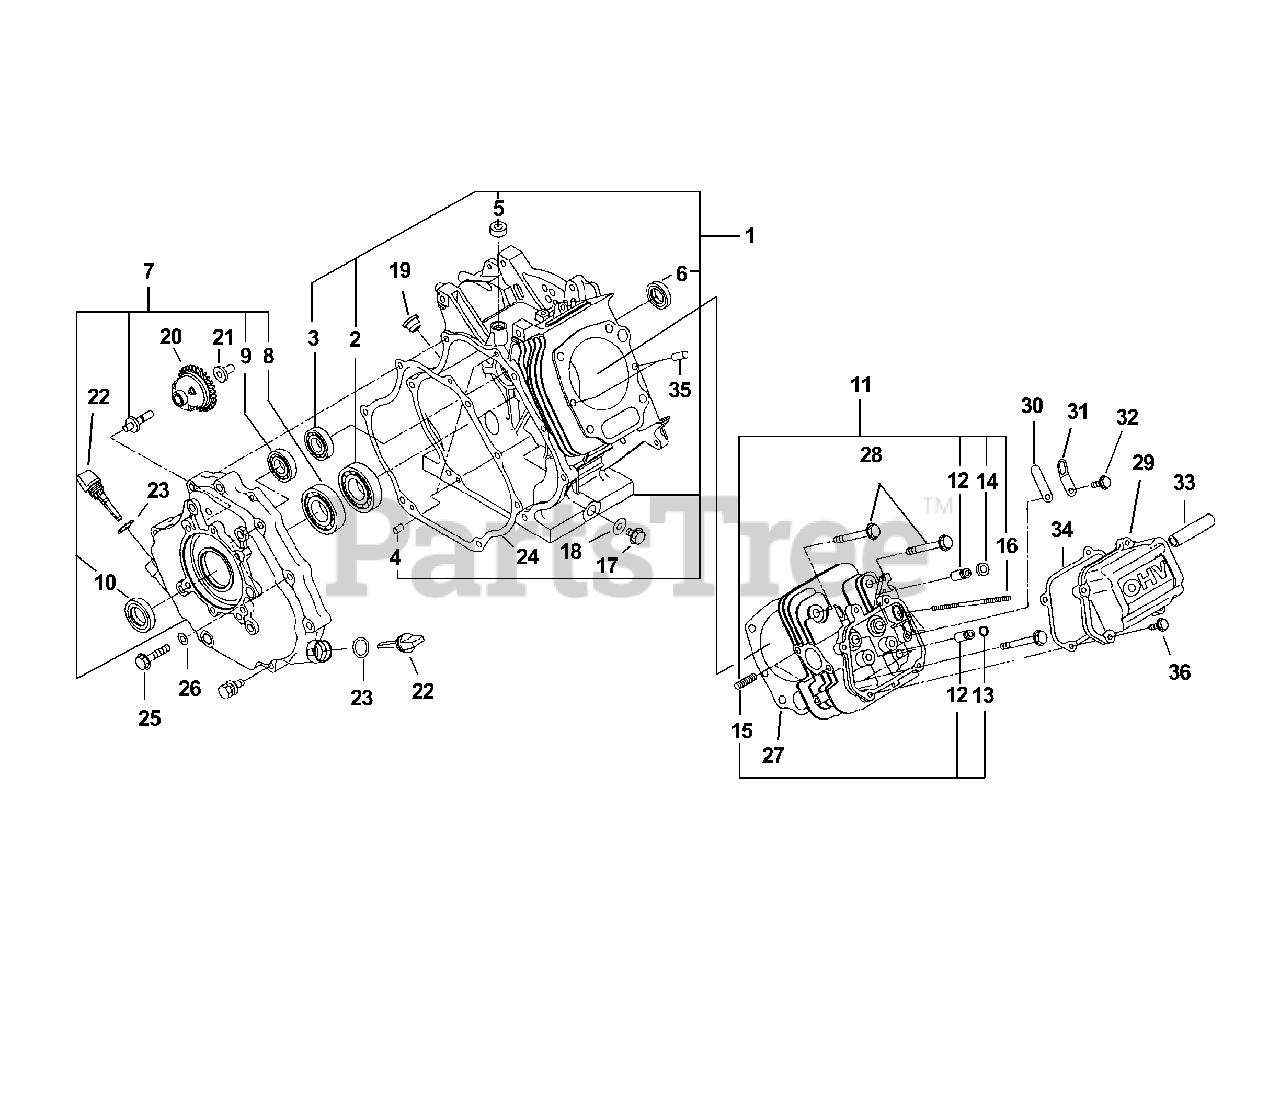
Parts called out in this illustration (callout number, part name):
1	Crankcase
2	Ball bearing
3	Ball bearing
4	Dowel pin
5	Oil seal
6	Oil seal
7	Main bearing cover
8	Ball bearing
9	Ball bearing
10	Oil seal
11	Cylinder head
12	Valve guide
14	Seal, Int valve
19	Plug, rubber
20	Governor gear cp
21	Governor sleeve
22	Oil gauge
24	Bearing cover gasket
25	Flange, bolt
27	Head gasket
28	Flange bolt
29	Rocker cover cp
30	Retainer plate
31	Leaf valve
32	Flange bolt
33	Rubber pipe
34	Gasket rocker cover
35	Dowel pin
36	Flange bolt
